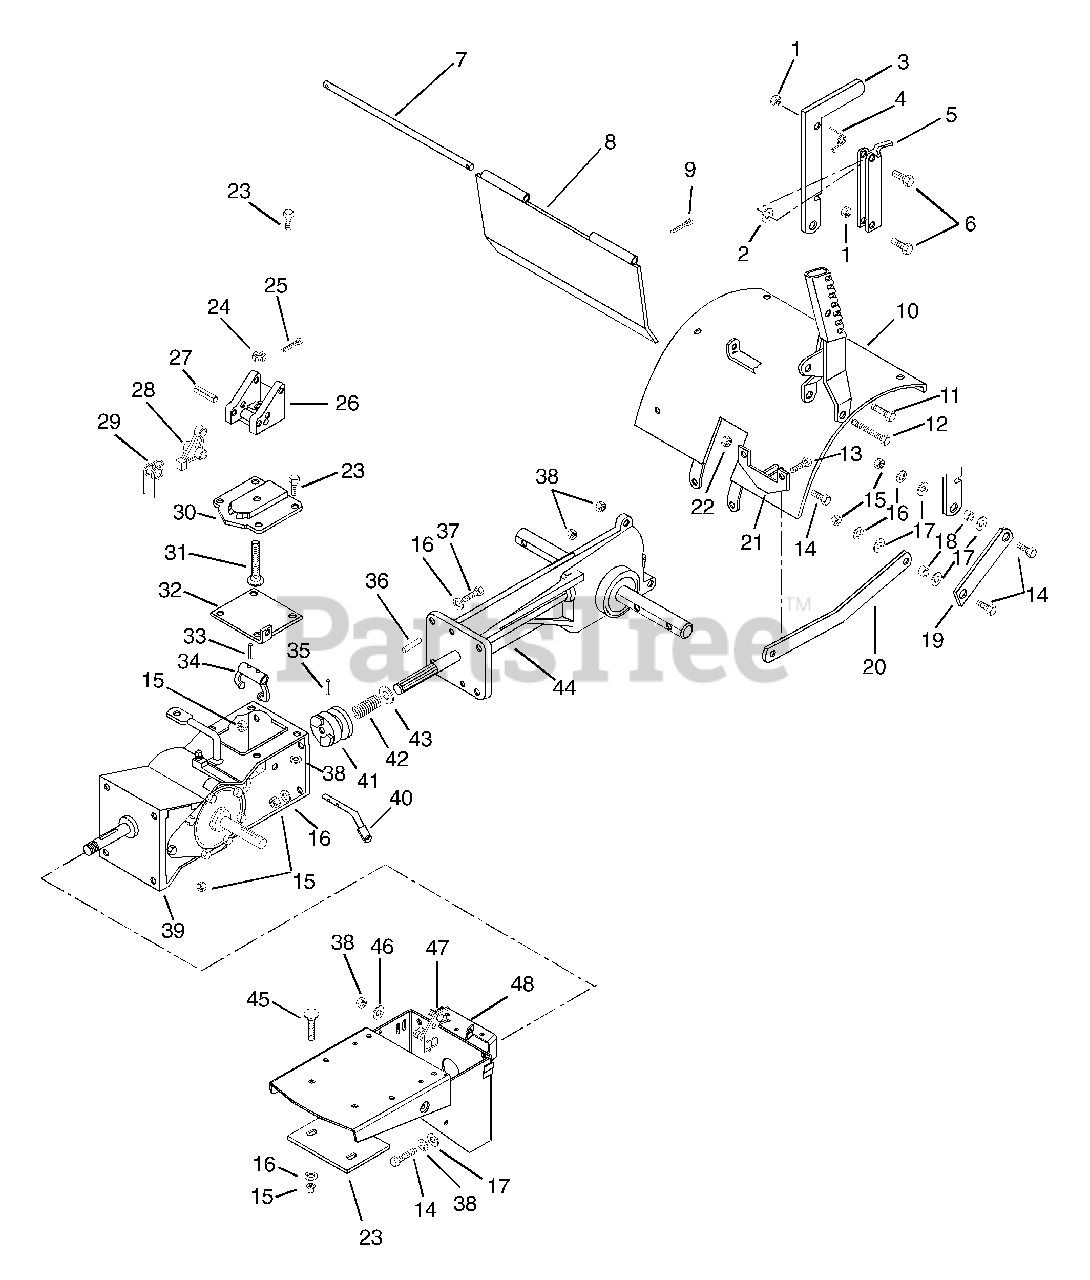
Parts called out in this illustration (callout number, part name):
1	@NUT-LK-CTR .25-20 YWZC
2	@WSHR-FL-STL.281X.62X.065 YWZC
3	HANDLE WELDMENT
4	SG-TORS .050X.25X2.33
5	TRIGGER
6	@BLT-HEX .25-20X1.25 GR5 YWZC
7	TAILBOARD PIN
8	TAILBOARD WELDMENT
9	@PIN-CTR .09X.50 EXTPRSQCT YWZ
10	TINE HOOD W/DECAL
11	@BLT-HEX .31-18X1.25 GR5 YWZC
12	@BLT-HEX .31-18X3.50 GR5 YWZC
13	@BLT-HEX .38-16X2.25 GR5 YWZC
14	@BLT-HEX .38-16X1.25 GR5 YWZC
15	@NUT-HEX .38-16 YWZC
16	@WSHR-LK .38X.094 REG YWZC
17	@WSHR-FL-STL.406X.812X.065 YWZ
18	SPACER BUSHING .63 X .38 X .27
19	CHISEL POINT
20	DRAG LINK
21	PIVOT BRACKET
22	@NUT-LK-CTR .38-16 YWZC
23	WEIGHT, WAFER
24	NUT-SL .50-13
25	@PIN-CTR .12X1.00 EXTPRSQCT YZ
26	BRACKET, HANDLEBAR
27	PIN-ROLL .313X2.00
29	SG-TORS .109X.88X2.25
30	PIVOT CAP
31	SWIVEL BOLT
32	PIVOT BRACKET
33	PIN-ROLL .188X1.00
34	CLUTCH FORK
35	PIN-ROLL .125X1.00
36	PIN-GRV .375X1.00 TP C
37	@BLT-HEX .38-16X1.75 GR5 YWZC
38	@NUT-LK-CTR .31-18 YWZC
39	TRANSMISSION GEARCASE ASSY
40	TINE ENGAGING FORK SHAFT
41	TILLER JAW CLUTCH
42	SG-COMP .080X.97X2.18 WLD14
43	WSHR-FL-STL .755X1.375X.125
44	TILLER GEAR CASE - C.I.
45	@BLT-RDHDSQNK .38-16X1.50 G5YZ
46	@WSHR-FL-STL.344X.688X.065YWZC
47	BELT FINGER BRACKET
48	FRAME 8HP
